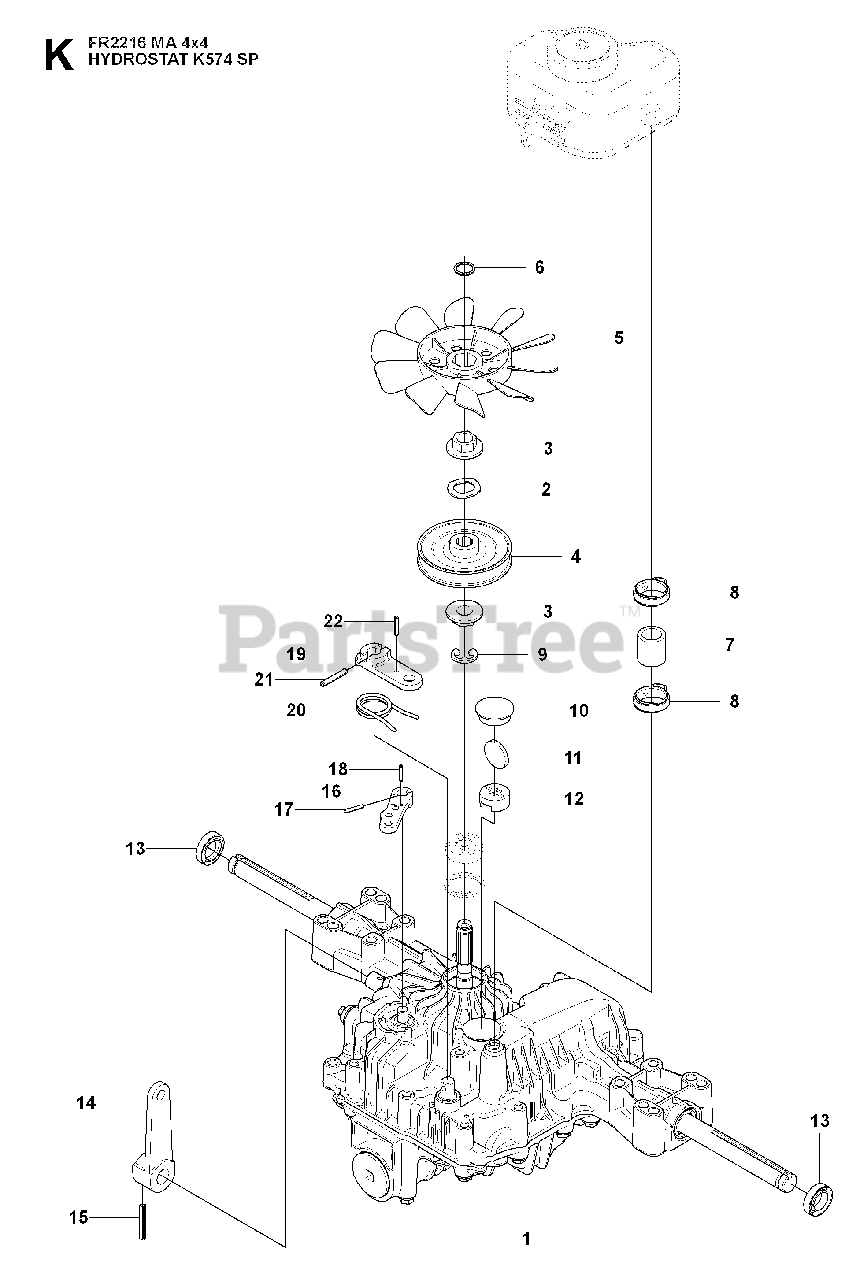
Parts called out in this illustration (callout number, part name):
1	HYDRAULMOTOR
2	WASHER **
5	FAN
6	RETAINING RING **
8	CLAMP
12	MAGNET HOLDER
13	SEALING
14	CONTROL LEVER
20	RETURN SPRING
